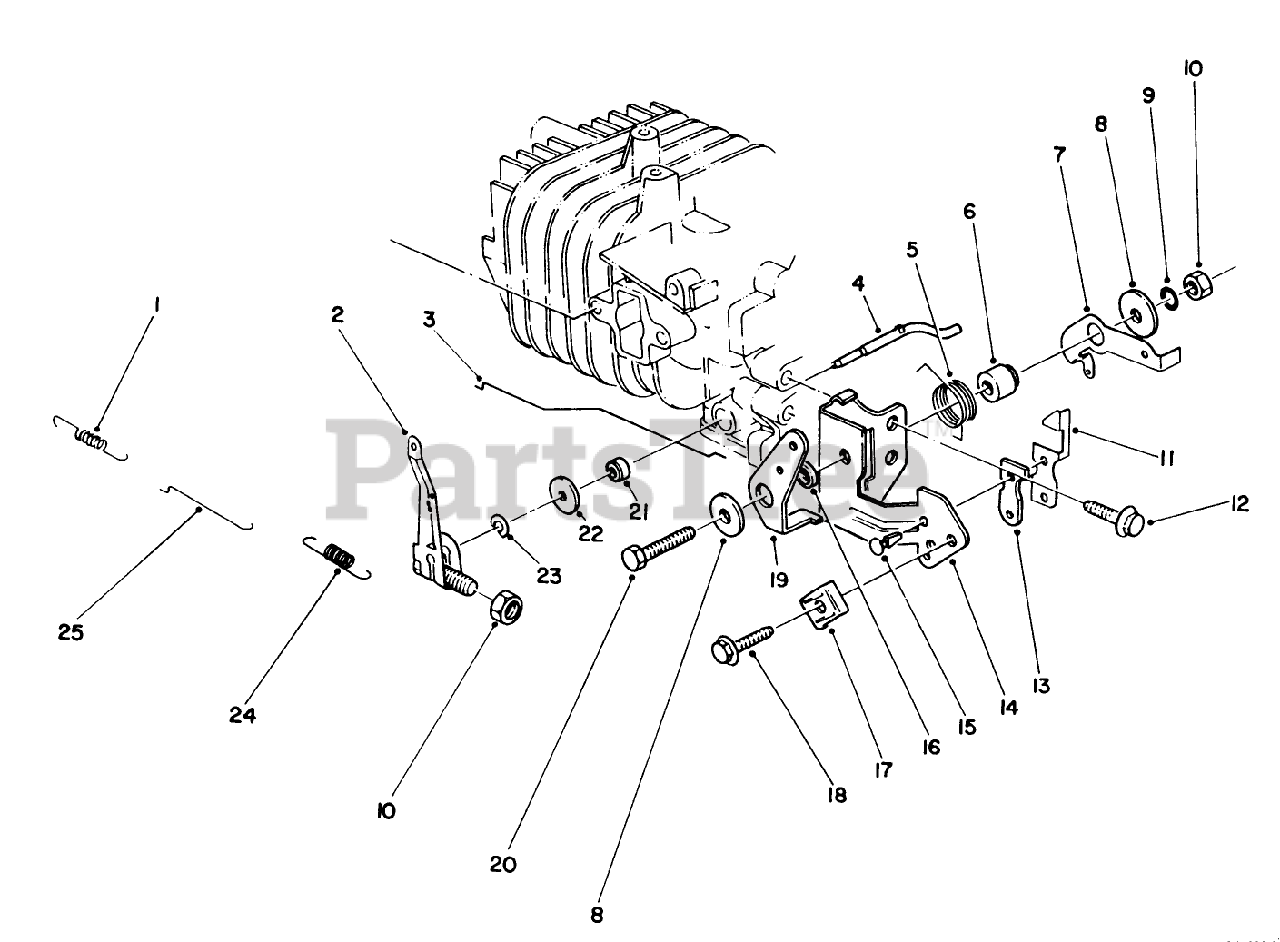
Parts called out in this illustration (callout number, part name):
1	SPRING
5	SPRING-CHOKE LEVER
7	LEVER-SPRING, GOVERNOR
8	WASHER
9	LOCKWASHER
11	TERMINAL-KILL SWITCH
13	INSULATOR-KILL SWITCH
14	BRACKET-THROTTLE, CONTROL
16	SPACER-CHOKE LEVER
17	CLAMP
21	SEAL-OIL
22	WASHER
24	SPRING-GOVERNOR
25	ROD-CARBURETOR
